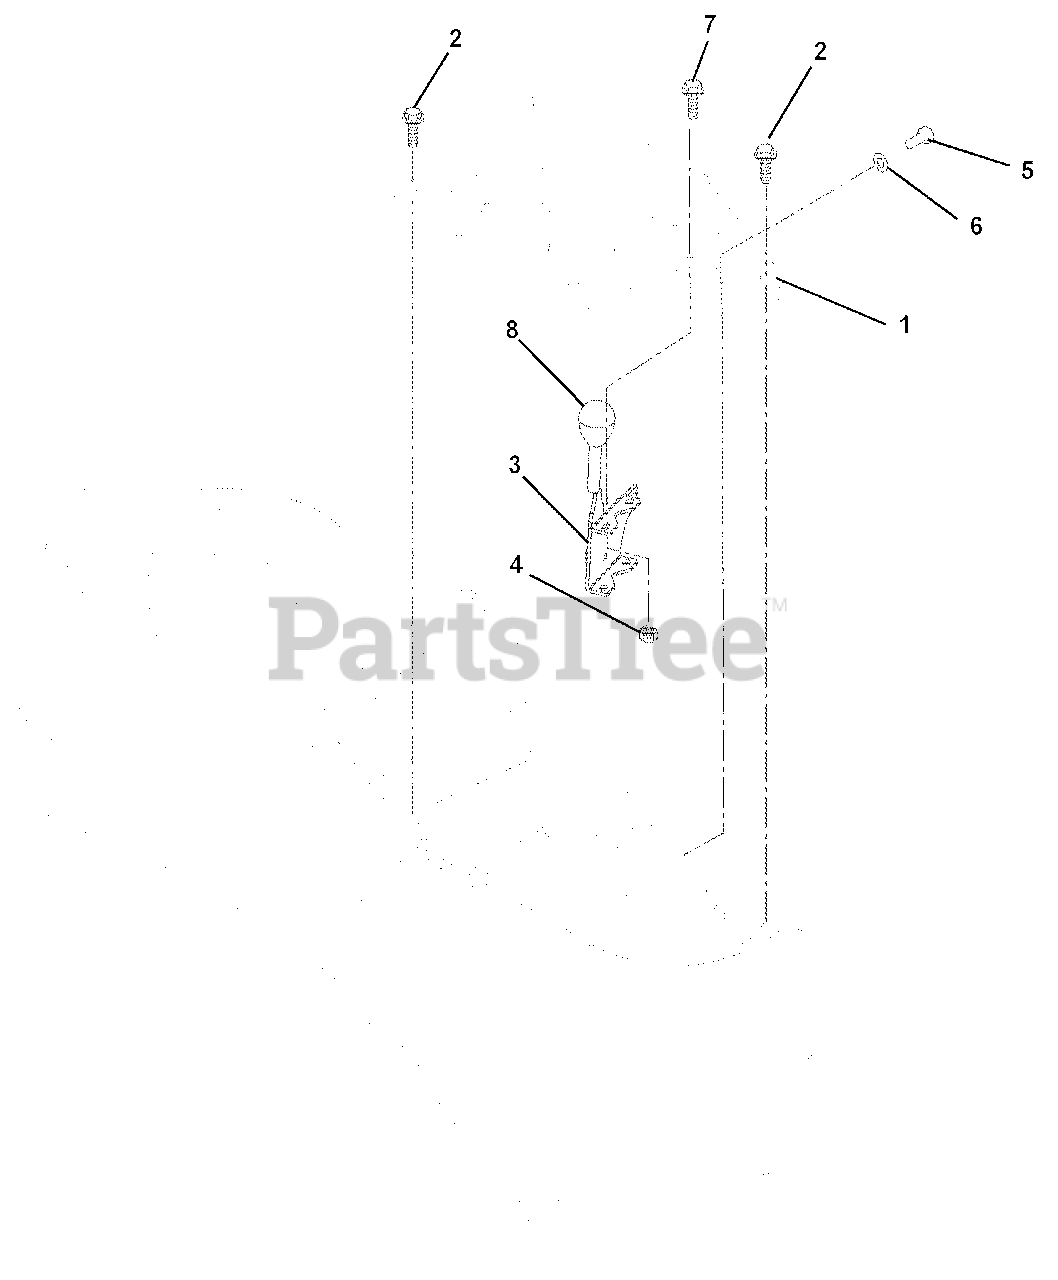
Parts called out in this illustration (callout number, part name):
1	PANEL-CONTROL PM200 DIESEL
2	SCR-MCH 10-24X.38 HWHSTAINLESS
3	CABLE-THROTTLE 47.37"
4	@NUT-LK-NYL 10-24 W/INSRT YWZC
5	@BLT-HEX .31-18X.75 GR5 YWZC
6	@WSHR-FL-STL.38X.875X.083 YWZC
7	@SCR-MCH 10-24X.50 HWH YWZC
8	KNOB-CONTROL-BLACK .38-16X.50
